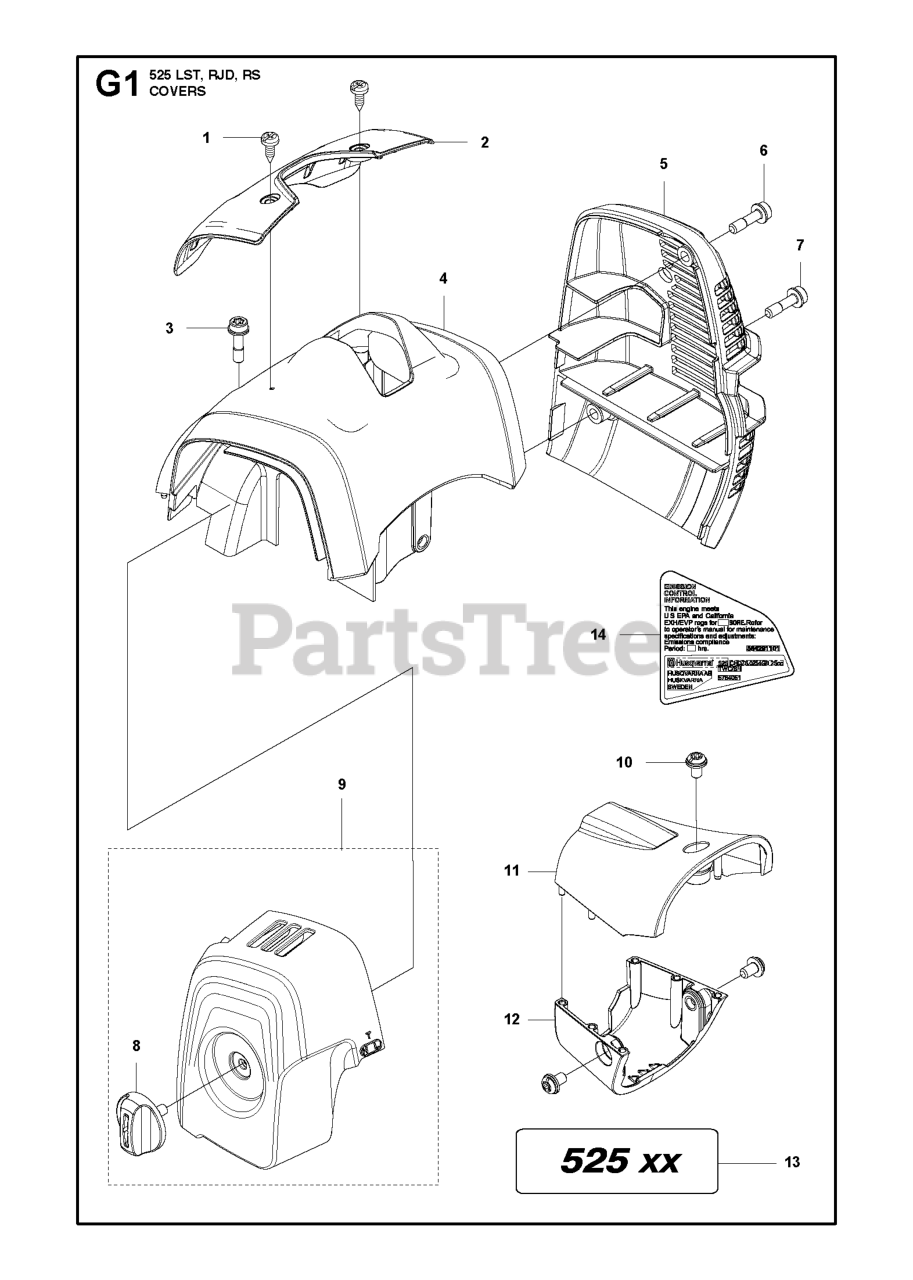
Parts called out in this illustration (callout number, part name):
2	ARM PROTECTION
3	BOLT
4	Cylinder
4	CYLINDER COVER
5	MUFFLER GUARD
6	BOLT
7	BOLT
8	KNOB CLEANER COLOR:GREY
9	FILTER COVER ASSY
11	COVER CLUTCH HOUSING,UPPER
12	COVER CLUTCH HOUSING,LOWER
